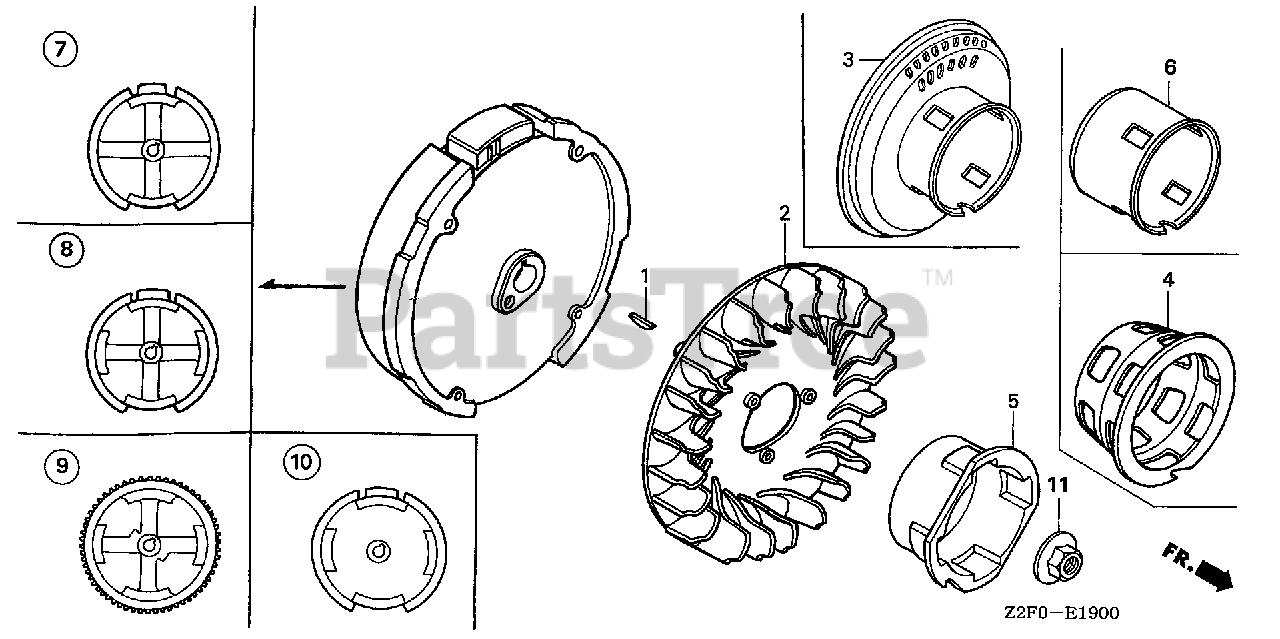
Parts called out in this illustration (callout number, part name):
1	KEY, SPECIAL WOODRUFF (25X18)
2	FAN, COOLING
6	PULLEY, STARTER
11	NUT, SPECIAL (14MM)
